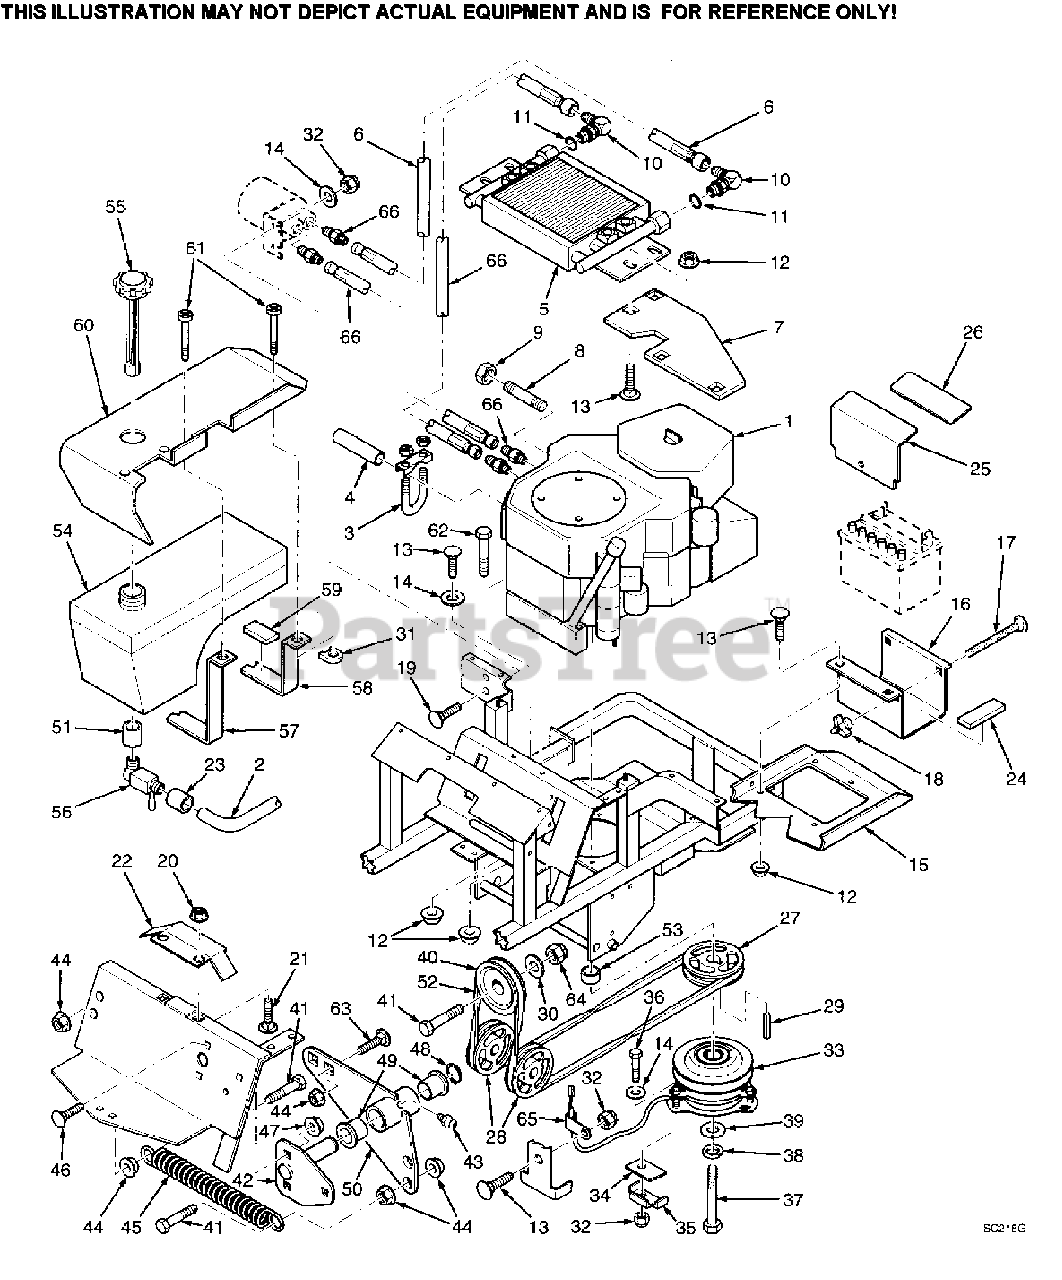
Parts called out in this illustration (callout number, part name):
2	FUEL HOSE, 23" LONG
3	MUFFLER CLAMP
4	TUBE, EXHAUST
5	OIL COOLER
6	HOSE, OIL COOLER
7	MOUNTING BRACKET, OIL COOLER
8	EXTENSION, 3"
9	PIPE CAP
10	ELBOW, 90 DEGREE 1/2-20 SAE TO 3/4-16
11	"O" RING
12	NUT, SERRATED FLANGE HEX HEAD 5/16-18
13	BOLT, CARRIAGE 5/16-18 X 3/4"
14	FLATWASHER, 5/16"(.313 X .875 X .083)
15	FENDER, LH
16	BATTERY BOX
17	BOLT, CARRIAGE 1/4-20 X 6"
18	WING NUT, 1/4-20
20	NUT, SERRATED FLANGE HEX 1/4-20
21	BOLT, CARRIAGE 1/4-20 X 3/4"
22	BELT GUARD
23	FUEL HOSE CLAMP
24	RUBBER PAD
25	BATTERY COVER
26	PAD, BATTERY COVER
27	PULLEY
28	PULLEY, PUMP
30	FLATWASHER, 3/8"(.391 X .938 X .105)
31	U-NUT, 1/4-20
32	NUT, ELASTIC STOP 5/16-18
33	ELECTRIC CLUTCH
34	RUBBER PAD, CLUTCH STOP
35	BACKING PLATE
36	BOLT, HEX HEAD 5/16-18 X 1-1/4"
37	BOLT, HEX HEAD 7/16-20 X 2.50
38	LOCKWASHER, 7/16"
39	FLATWASHER, 7/16" SPECIAL
40	IDLER, PULLEY
41	BOLT, HEX HEAD 3/8-16 X 1.75"
42	PIVOT WELDMENT, IDLER ARM
43	GREASE FITTING
44	NUT, SERRATED FLANGE HEX 3/8-16
45	SPRING, PUMP DRIVE IDLER
46	BOLT, CARRIAGE 5/16-18 X 3/4
47	NUT, SERRATED FLANGE HEX 5/16-18
48	RING, RETAINING 1.125 DIAMETER EXTERNAL "E"
49	BUSHING, 1.125 SINTERED
50	IDLER ARM WELDMENT, PUMP DRIVE
51	BUSHING, FUEL TANK VALVE
52	BELT, PUMP DRIVE
53	SPACER, CRANKSHAFT
54	FUEL TANK(INCLUDES SHUT-OFF VALVE)
55	FUEL TANK CAP
56	FUEL SHUT-OFF VALVE
57	FUEL TANK STRAP, LONG
58	FUEL TANK STRAP, SHORT
59	RUBBER PAD
60	FENDER ASSEMBLY, RH(WITH DECAL)
61	SCREW, MACHINE 1/4-20 X 2" PHILLIPS HEAD
62	BOLT, SERRATED FLANGE HEX HEAD 5/16-18 X
63	BOLT, CARRIAGE 7/8-16 X 1.50"
64	NUT, ELASTIC STOP 3/8-16
65	CLAMP, .50 ID
66	KOHLER FITTINGS, PURCHASE FROM KOHLER
